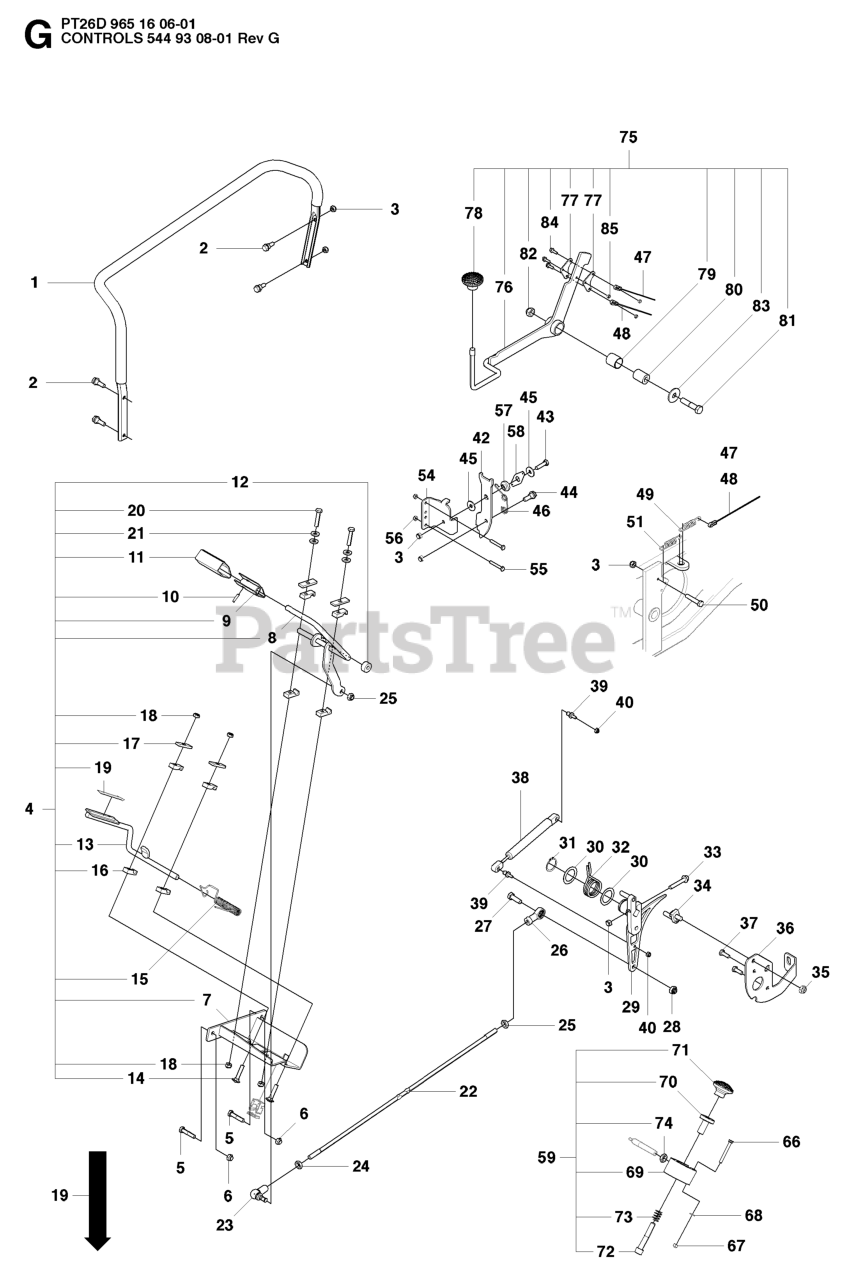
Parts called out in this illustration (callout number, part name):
1	HANDLE ASSY
3	LOCKNUT M8
6	LOCKNUT M8
11	PEDAL RUBBER
14	Screw Mvbf 8 X 40
18	NUT
21	WASHER - 15X7.3X1.6
25	NUT
28	NUT
30	WASHER SPACER 32X45X1,0
33	SCREW
40	LOCKNUT M6
43	SCREW
50	SCREW
56	LOCKNUT M6
67	LOCKNUT M6
68	WASHER
71	KNOB
78	KNOB
79	BUSHING
84	SCREW M6S 5X20
85	LOCKNUT M5
